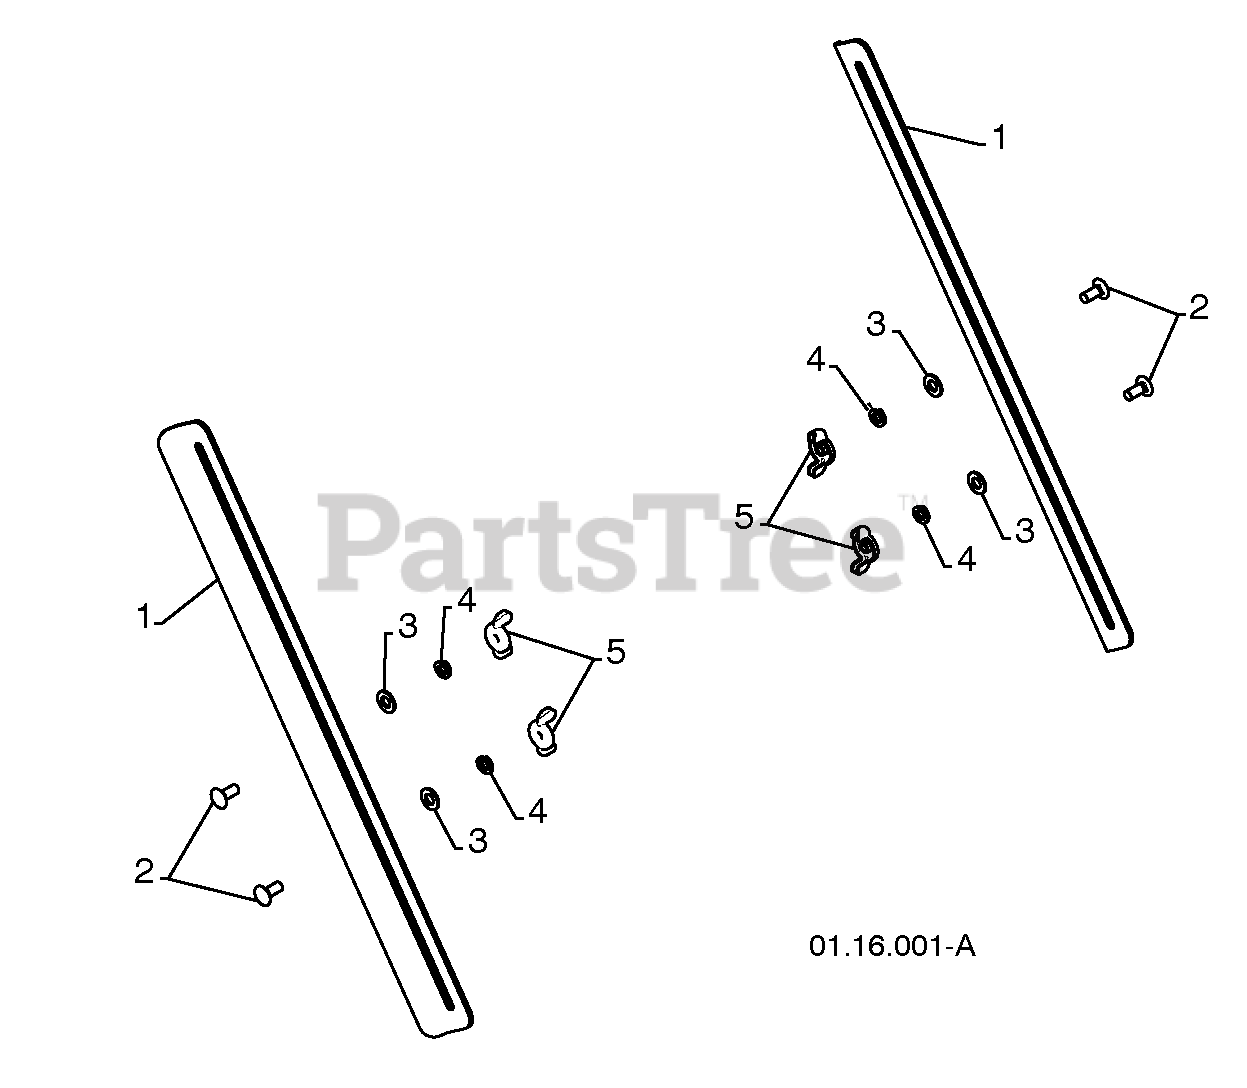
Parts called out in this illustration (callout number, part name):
1	DRIFT CUTTER BAR
2	CARRIAGE BOLT 5/16-18 X .750
3	PLASTIC WASHER
4	LOCKWASHER 5/16
5	NUT 5/16-18
